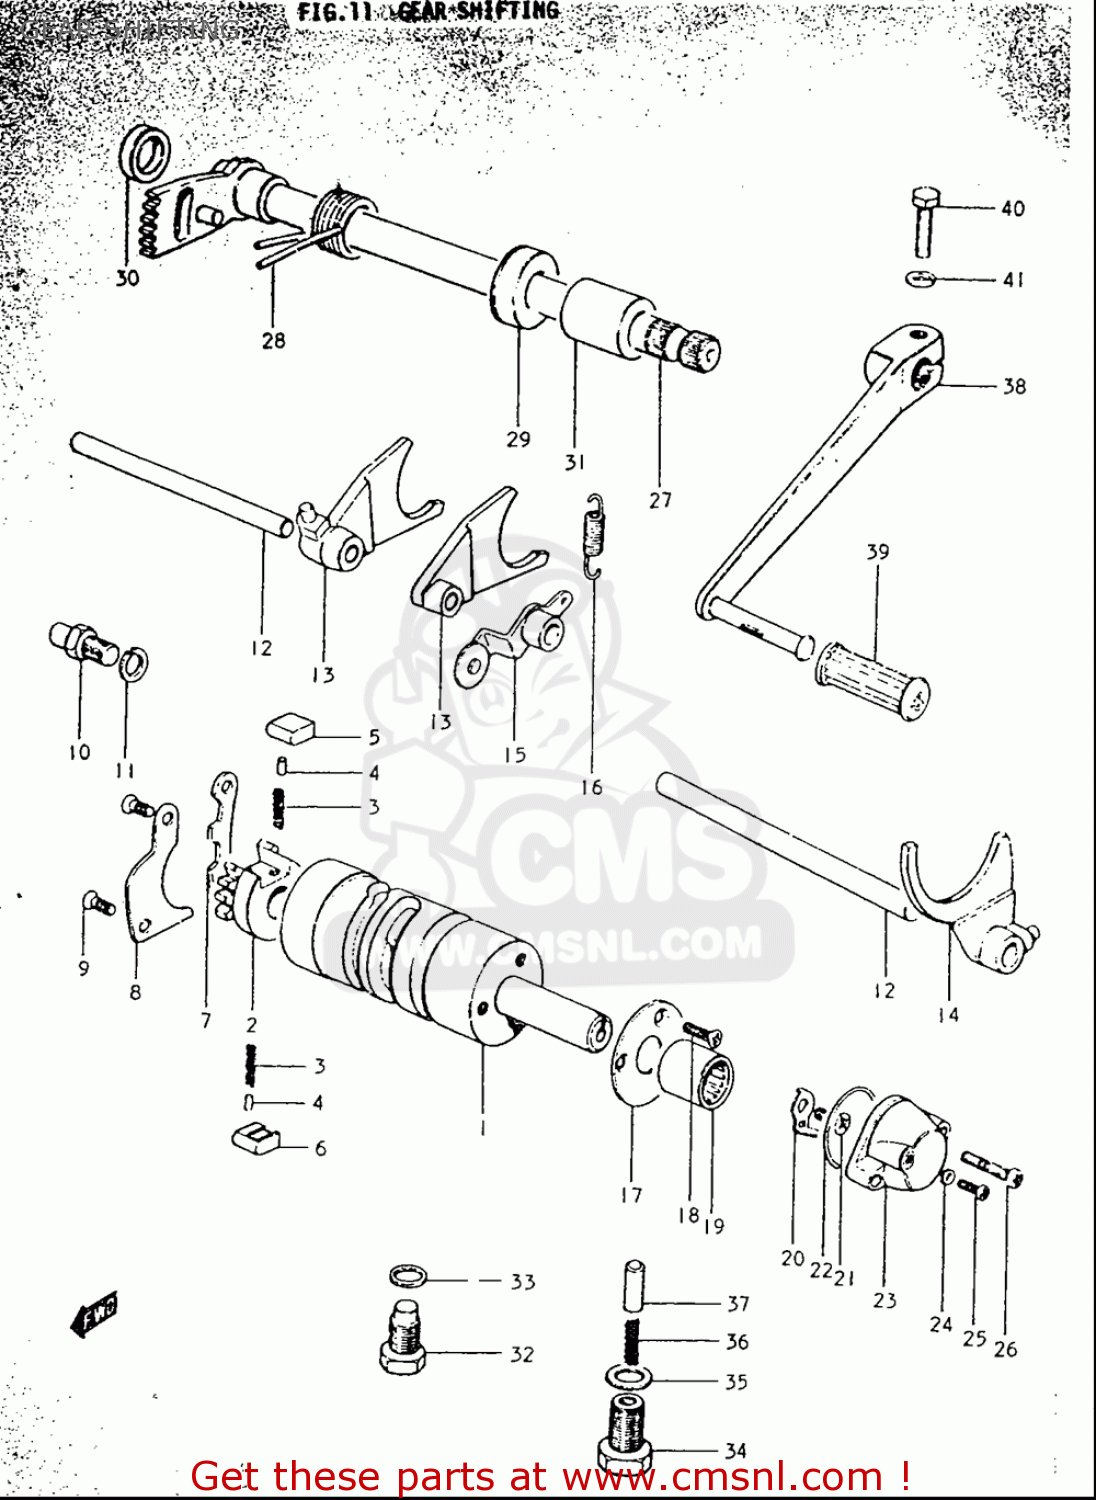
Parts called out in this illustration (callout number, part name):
2	GEAR,GEAR SHIFT CAM DRIVEN
3	SPRING
4	PIN(5X8)
5	PAWL,GEAR SHIFT NO.2
6	PAWL,GEAR SHIFT NO.1
8	LIFTER,GEAR SHIFT PAWL
10	STOPPER,GEAR SHIFT ARM
11	WASHER,LOCK
12	SHAFT,GEAR SHIFT FORK
15	STOPPER,GEAR SHIFTING
16	SPRING
19	ROLLER BEARING (16X22X1
20	CONTACT,GEAR SHIFT SWITCH
22	O RING(D:1.9,ID:27.7)
23	BODY,GEAR SHIFT SWITCH
24	WASHER
25	SCREW
28	SPRING
29	SEAL,OIL (12X22X9)
31	CUSHION
33	GASKET(14X19.2X2) (NAS)
34	HOUSING,GEAR SHIFT CAM STOPPER
35	GASKET(14X19.2X2) (NAS)
36	SPRING
37	STOPPER,GEAR SHIFT CAM
39	RUBBER,GEAR SHIFT PEDAL
40	BOLT
41	WASHER,LOCK
